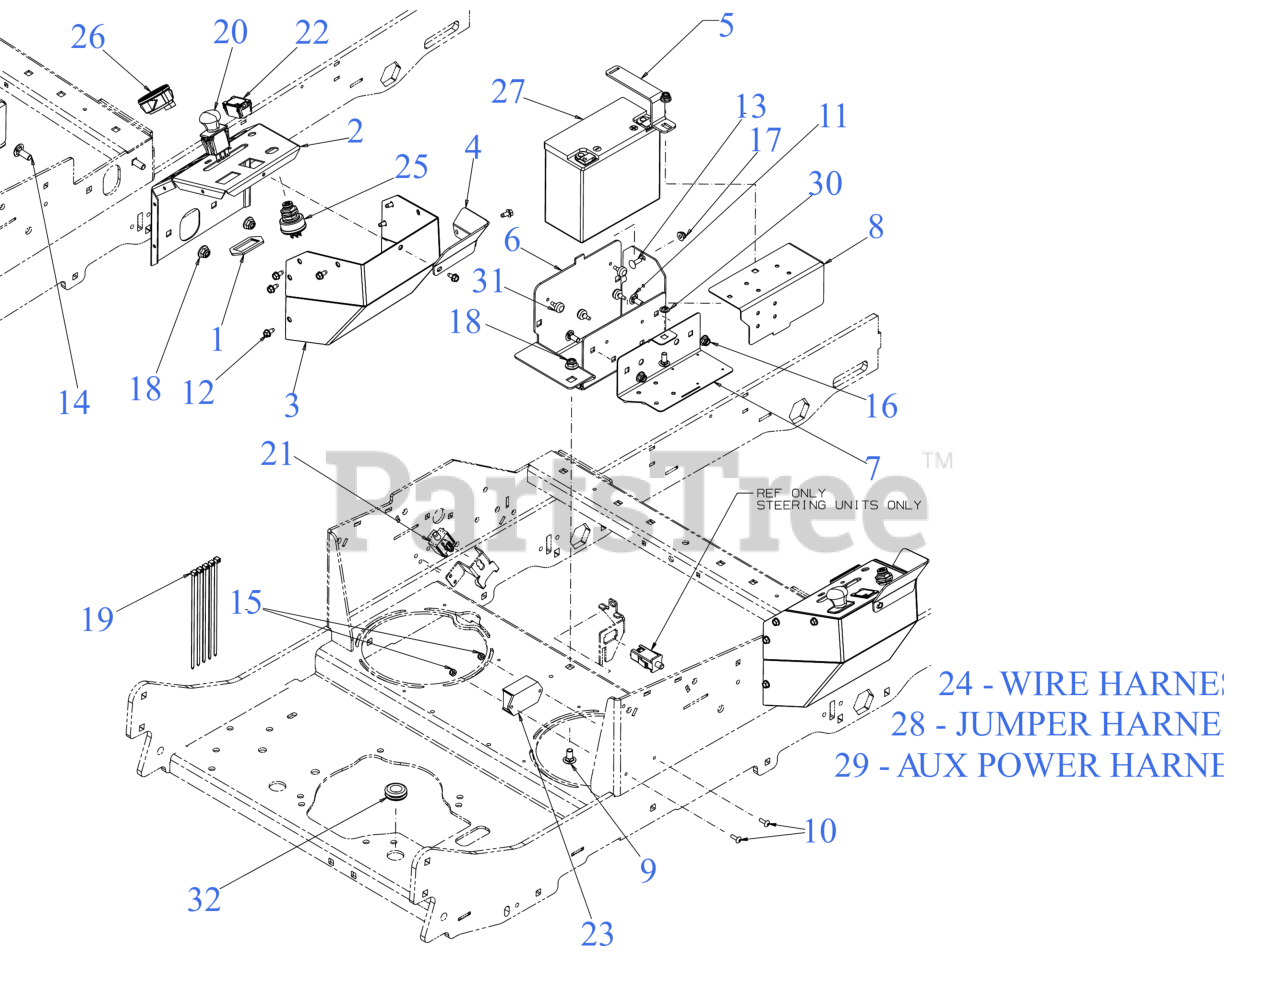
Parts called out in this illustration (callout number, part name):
1	BRACKET-PTO SWITCH
2	CONTROL POD - RH
5	BATTERY SUPPORT BRACKET
6	BATTERY MOUNT BRACKET
7	MOUNT BRACKET (LOWER)
8	COVER BRACKET (UPPER)
9	CARRIAGE BOLT 3/8-16 x .750 GR5
10	SCREW #10-24 x .62
11	CARRIAGE BOLT 5/16-18 x .75
12	SCREW 1/4-20 X.500
13	SCREW 1/4-20 x .75 GR5
14	CARRIAGE BOLT 3/8-16 x 1.00 GR5
16	FLANGE LOCK NUT 5/16-18
17	FLANGE LOCK NUT
19	7" CABLE TIE
20	PTO SWITCH (BLACK KNOB) TEXT SYM
21	3 POLE SWITCH ( NC-NO-NO)
23	CONTROL PANEL (SOFT CLUTCH)
24	WIRE HARNESS ASSEMBLY (KOH/KAW EFI)
25	KEY SWITCH (3 POSITION)
25	PRO-Z KEY SET
26	DUAL FUEL GAUGE
27	BATTERY (300 CCA)
28	JUMPER HARNESS (W/RELAY)
29	AUX POWER HARNESS
31	BUMPER, .62 DIA x .3
32	RUBBER GROMMET
